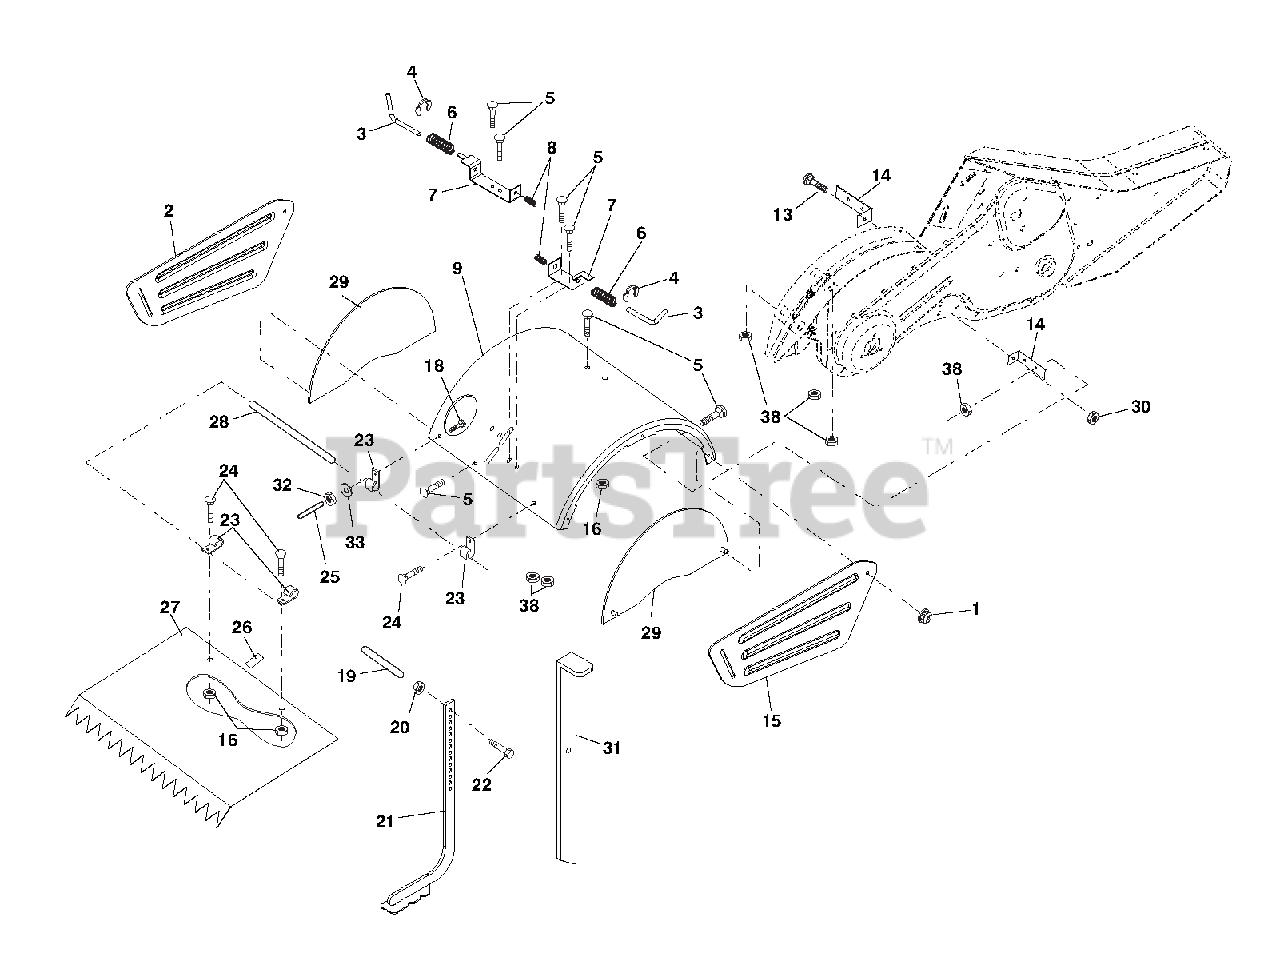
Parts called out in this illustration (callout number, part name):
1	Nut, Lock Hex Flange 5/16-18 u
2	Shield, Side, Outer L. H.
3	Pin, Stake, Depth
4	Ring, Klip
5	Bolt, Carriage, Gr. 5 5/16-18
7	Bracket, Latch
8	Spring, Depth Stake
9	Shield, Tine
13	Bolt, Carriage 5/16-18 x 1-1/4
14	Bracket, Shield Tine
15	Shield, Side, Outer RH
16	Nut, Hex Flange 1/4-20 unc
18	Bolt, Carriage 1/4-20 x 1-1/4
20	Nut, Hex 3/8-16
21	Stake, Depth
22	Bolt, Hex 3/8-16 x 2
24	Bolt, Carriage 1/4-20 x 1/2
25	Cap, Vinyl
26	Pad, Idler
27	Shield, Leveling
28	Pin, Hinge
29	Shield, Side
30	Nut, Hex, Flangelock
31	Stake, Drag
32	Nut, Fin, Hex 1/4-20 unc
33	Washer, Lock 1/4
38	Nut, Keps 5/16-18 unc
